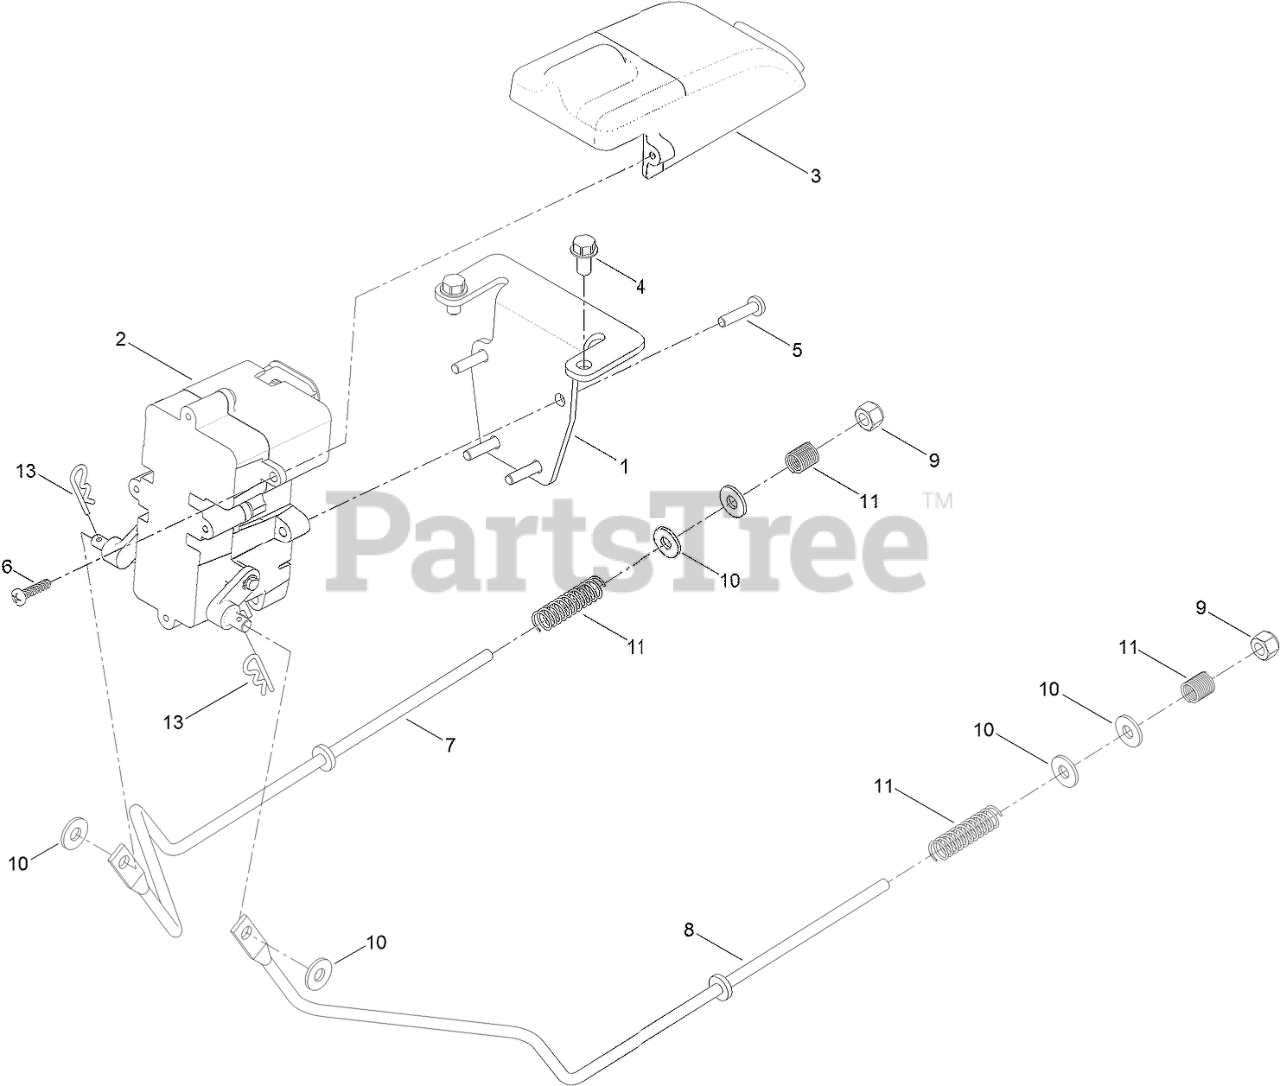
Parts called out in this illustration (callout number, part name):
1	BRACKET-MOUNT, BRAKE
2	Brake Box ASM
3	COVER-CONNECTOR
4	SCREW-HWH
5	SCREW-PPH
6	SCREW-PPH
7	ROD-BRAKE, WIDE (RH)
8	ROD-BRAKE, WIDE (LH)
9	NUT-LOCK, NI
10	WASHER
11	SPRING-COMPRESSION
13	PIN-COTTER
